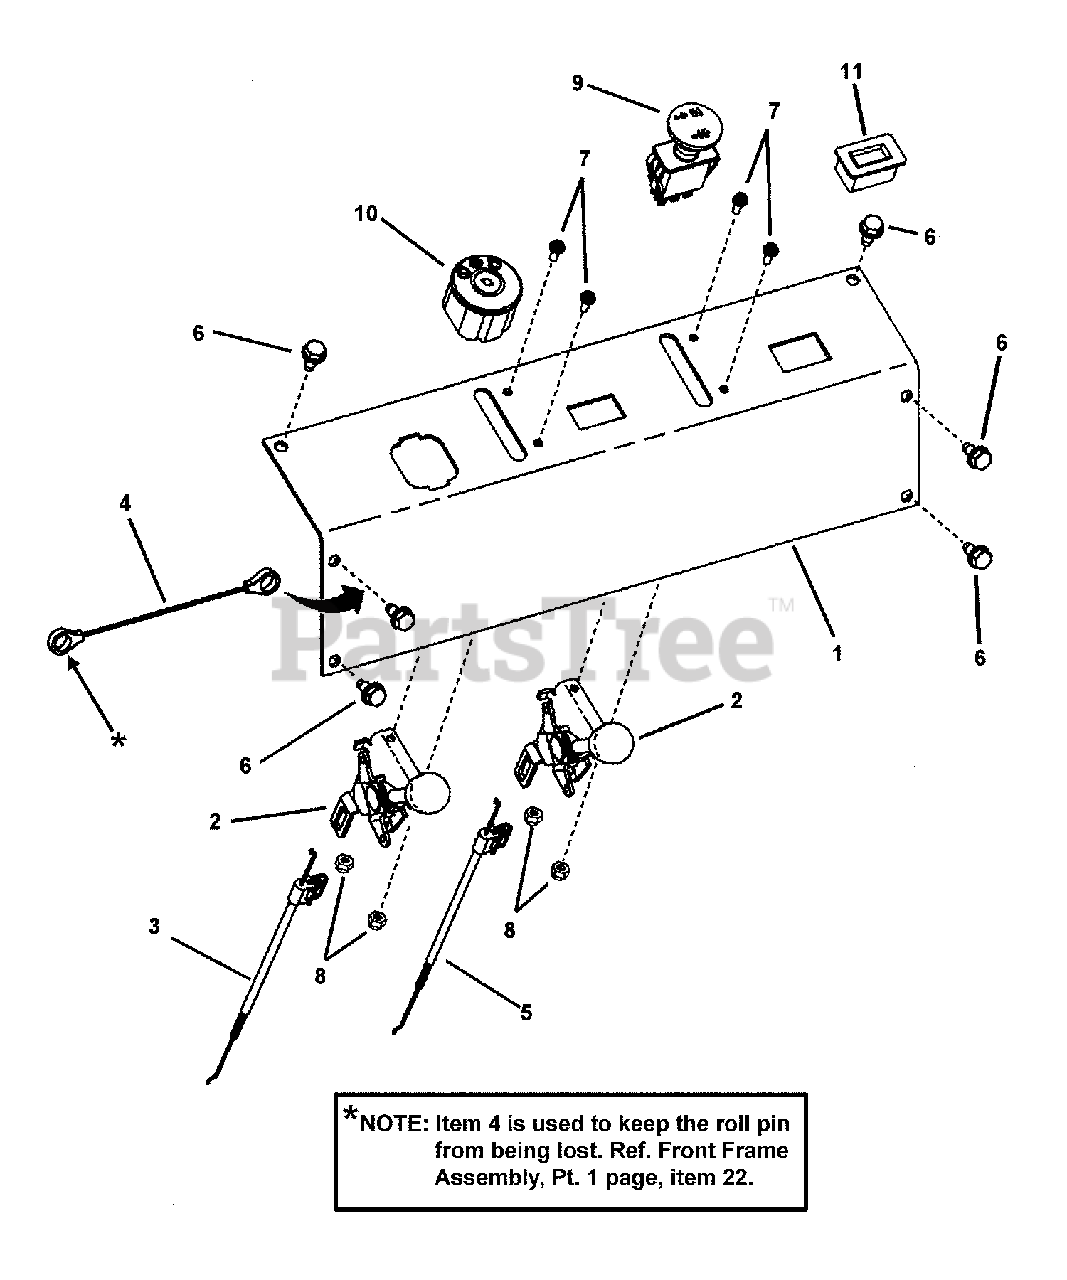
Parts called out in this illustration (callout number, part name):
1	CONTROL PANEL
2	CONTROL LEVER, Throttle/Choke
3	CONTROL CABLE, Throttle
4	STRAP, Tether
5	CONTROL CABLE, Choke
6	SCREW, 5/16-18 x 5/8" Hex Washer Self-Tap
7	SCREW, #10-32 x 5/8" Hex Washer Self-Tap
8	NUT, #10-32 Nyloc
9	SWITCH, PTO, Yellow
10	SWITCH, Ignition
11	HOUR METER w/Flash Alerts
